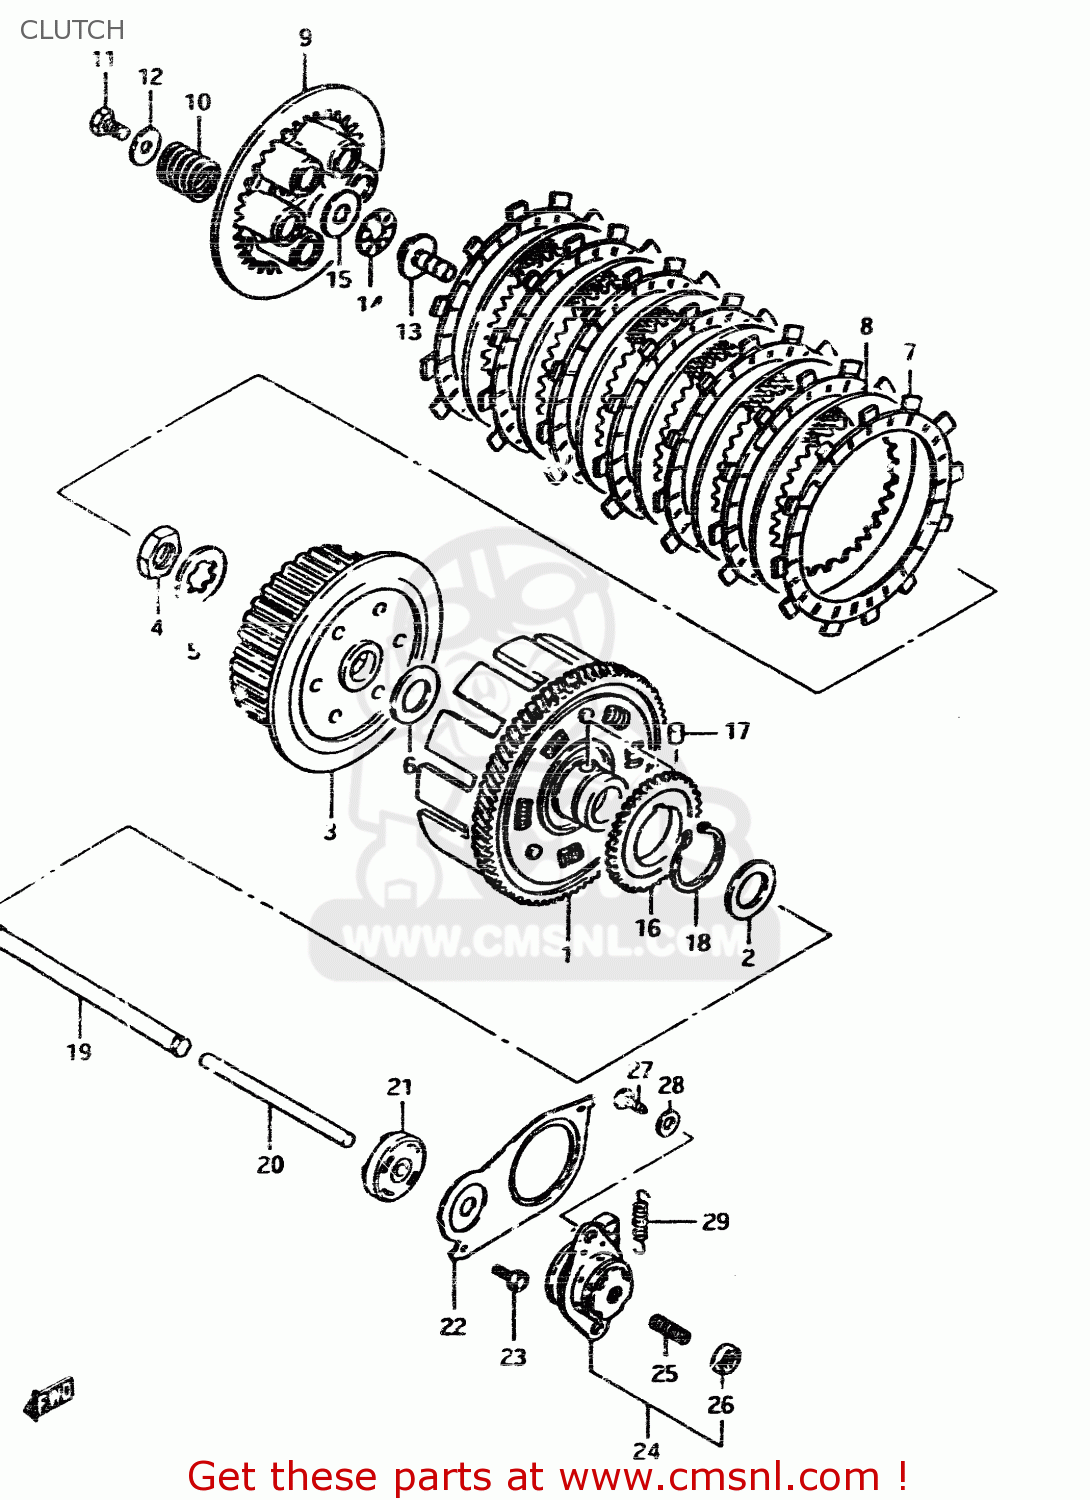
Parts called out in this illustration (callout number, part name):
1	GEAR ASSEMBLY,PRIMARY DRIVE
2	WASHER
3	HUB,CLUTCH SLEEVE
4	NUT (20MM)
5	WASHER,LOCK
6	WASHER(20X44X3)
7	PLATE,CLUTCH DRIVE (MCA)
8	PLATE,CLUTCH DRIVEN (NAS)
9	DISC,CLUTCH PRESSURE
10	SPRING
11	BOLT, UPPER
12	WASHER
13	PIECE,CLUTCH PUSH
14	BEARING(15X28X2)
15	WASHER
16	GEAR,OIL PUMP DRIVE
17	PIN(6X6)
18	CIRCLIP
19	ROD,CLUTCH PUSH
20	ROD,CLUTCH PUSH
21	SEAL,OIL(6X34X10)
22	PLATE,CLUTCH PUSH ROD
23	BOLT
24	SCREW ASSY,CLUTCH RELEASE
25	SCREW
26	NUT 6MM
27	SCREW
28	WASHER
29	SPRING
